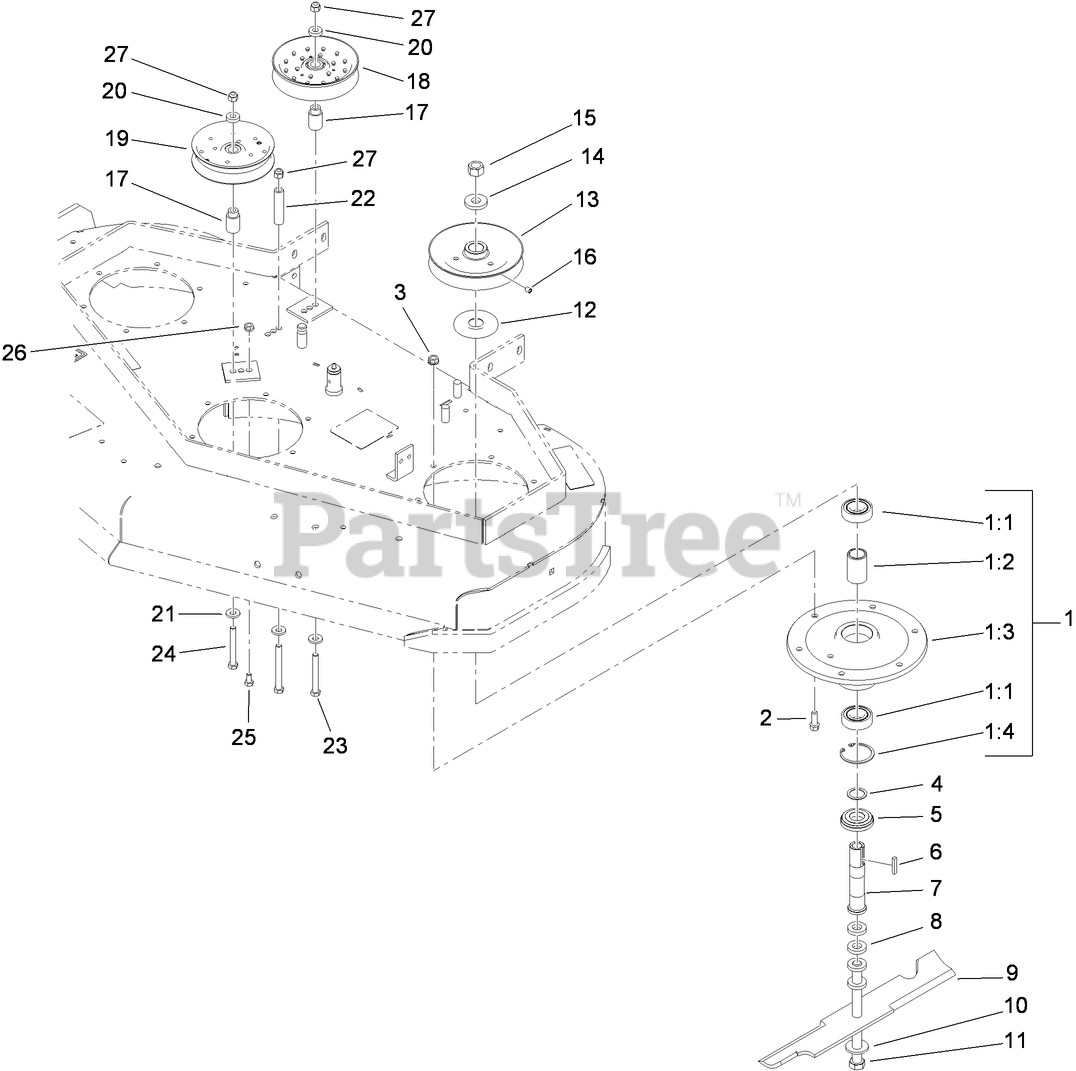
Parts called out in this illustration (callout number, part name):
1	SPINDLE HOUSING ASM
1:1	BEARING
1:2	SPACER-BEARING
1:3	HOUSING-SPINDLE
1:4	RING-SNAP
2	SCREW-HWH
3	NUT-HF, NI
4	WASHER-SPACER
5	SPACER-GUARD, BOTTOM
7	TUBE-SPINDLE, SHORT
8	SPACER
9	BLADE-16.5 INCH (HIGH FLOW)
10	WASHER-SPRING
11	SCREW-CAP, HH
12	Guard-Bearing, Top
13	SHEAVE
14	WASHER-RETAINER, SHEAVE
15	NUT-HEX
16	SCREW-SET
17	BUSHING-IDLER
18	IDLER-PULLEY, FLAT
19	PULLEY-IDLER
20	SPACER
21	WASHER-BELLEVILLE
22	SPACER
23	SCREW-HH
24	SCREW-HH
25	SCREW-HH
26	NUT-HF
27	NUT-LOCK, NI
